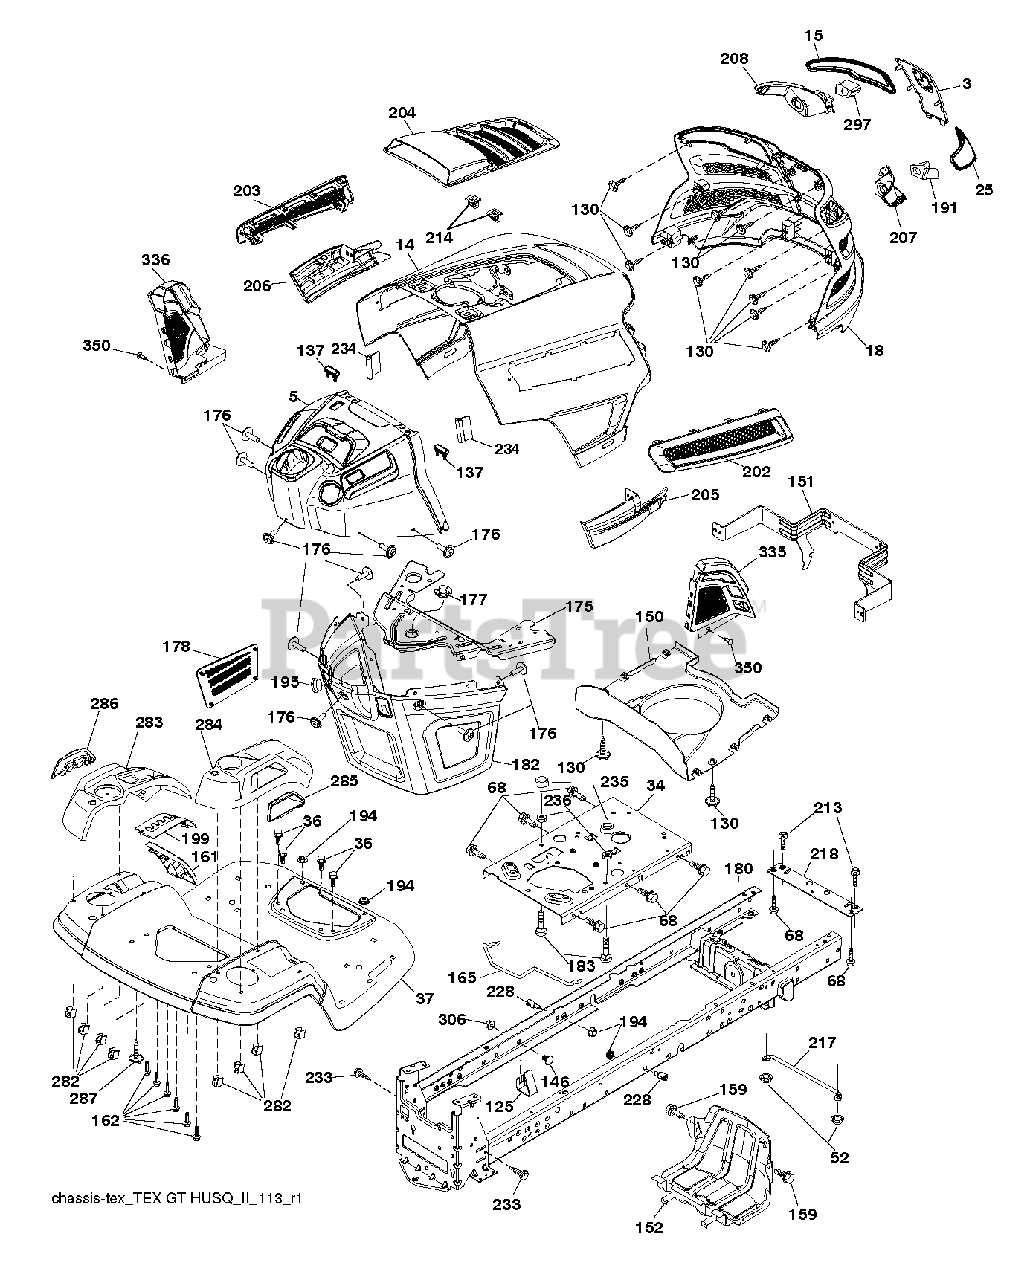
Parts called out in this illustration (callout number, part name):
3	APPLIQUE.SUBASM.GT.HUSQ.II
5	UPPER.ASSY.GT2.498.GRY
14	HOOD.ASM.HUSQVARNA.GT.TEX.ORAN
15	LENS.HEADLIGHT.LH.GTII.2011
18	GRILLE.SUBSTRATE.2011.
25	LENS.HEADLIGHT.RH.GTII.2011
34	PLATE.ENGINE.WELDED.CHASSIS
36	SCREW 5/16"
37	FENDER.TLT.FS.W/CPH/FW/RSF.668
52	LOCKNUT
68	SCREW LT
125	CLIP.FUEL.LINE
130	SCREW.#10 X 0.750.BOS
137	BUMPER DASH
146	BOLT.RDHD.SHT.SQNK.3/8-16X5/8
150	AIR.DUCT.GTV.BLACK
151	BRACKET.PIVOT.HOOD.GT.HUSQ.II
152	SHIELD.BROWNING.PNT.GT.V2
159	SCREW, 3/8-16X3/4
161	WINDOW.FUEL.LT.HUSQ.TEX.498
162	SCREW.HI-LO.CONSOLE
165	SUPPORT.TANK.REAR.W/TEX
175	PLATE.CROSSMEMBER.HUSQ
176	SCREW.#10-24X5/8.RN.QU
177	BUSHING, STEERING
178	CARGO.ASM.NET.TXGT.W/C
180	CHASSIS
182	DASH.LOWER.COMMON.12V.ADAPTOR
183	BOLT.5/16-18X1-1/4 FULL THD
191	INSERT.REFLECTIVE.RH.HUSQ.GTII
194	NUT LOCK HEX FLANGE 5/16-18
195	PLUG.HOLE.DASH.LOWER.12V.BLK
199	PLATE.DECK.LIFT.HUSQ.LT
202	VENT.SIDE.RH.GT.HUSQ.II.
203	VENT.SIDE.LH.GT.HUSQ.II.498
204	VENT.TOP.HUSQ.GT2
205	SIDE.TRIM.RH.GT.HUSQ.II
206	SIDE.TRIM.LH.GT.HUSQ.II.GRAY
207	BEZEL LIGHT.RH.GT.II.MYLAR
208	BEZEL LIGHT.LH.GT.II.MYLAR
213	BOLT
214	CLIP.RETAINER.TINNER.
217	ROD.PIVOT.HOOD
218	X-PIECE.HOOD.STOP.NON/
228	STUD.FASTNER.W/ANTI-ROTATE
233	BOLT.SHOULDER
234	BUMPER.HOOD.TEX.HUSQVARNA
235	SPACER FENDER
236	NUT.CENTERLOCK.5/16-
282	CLIP.RETAINER.CONSOLE.LT.HUSQ
283	CONSOLE.DECK.LIFT.R.SDFL.HUSQ
284	CONCOLE.CNTRL.PDL.HUSQ.LT.498
285	CONSOLE INSERT RH
286	CONSOLE.INSRT.LH.HUSQ.LT.BLACK
287	SCREW 1/4X20
297	INSERT.REFLECTIVE.LH.HUSQ.GTII
306	NUT LOCK FLG 3/8-16 UNC
335	COVER.LOWER.DASH.RH.BLACK
336	COVER-LH.LOWER.DASH.GT2.BLACK
350	CLIP.X-MAS.TREE
